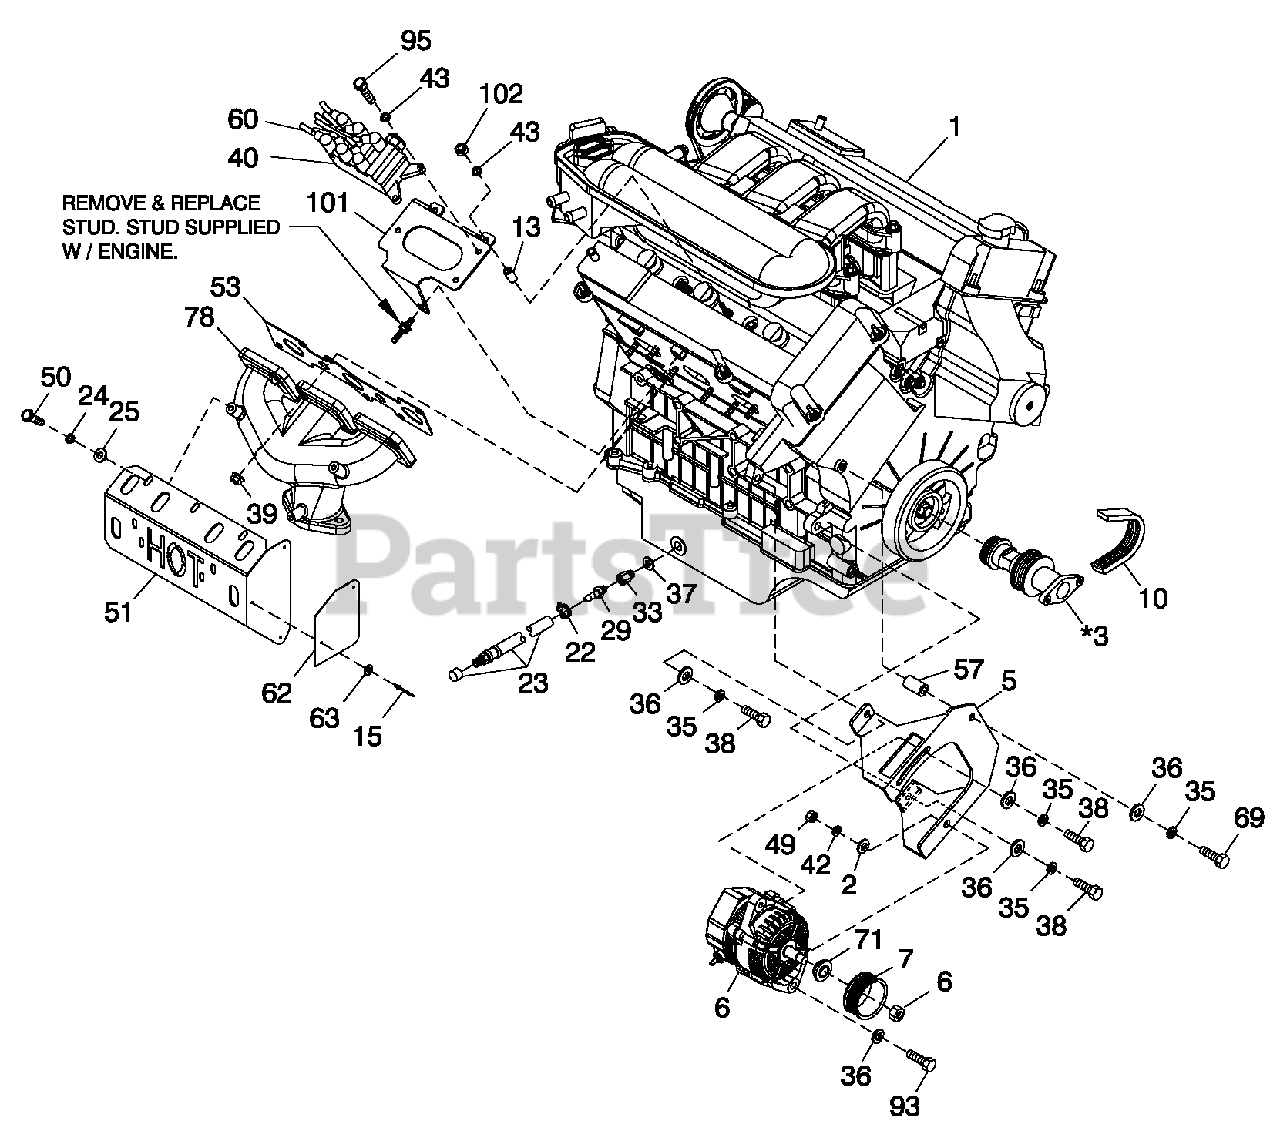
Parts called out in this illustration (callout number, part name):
1	ENGINE FWD MAKE
2	WASHER FLAT 3/8-M10 ZINC
3	ADAPTER CRANKSHAFT
4	TIE WRAP UL 17.7 X .35 BLK HT
5	BRACKET DC ALTERNATOR
6	ALTERNATOR DC W/OUT PULLEY
7	PULLEY 80 OD DC ALTERNATOR
8	SUPPORT COOLANT TUBE
9	OIL FILTER
10	BELT SERPENTINE 28.92"
11	SPACER FLEX PLATE
12	WASHER SHAKEPROOF EXT 5/16 STL
13	SPAC ER.19 X .31 X .50 PL
14	SWITCH HI-TEMP 245D X 3/8 NPT
15	RIVET POP .125 X .400 AL
16	STARTER 12 VOLT
17	COVER IAC ACTUATOR
18	ADAPTER ENGINE
19	FLEX PLATE 2 POLE
20	BSHG RDCR HEX 3/8 TO 1/8 GALV
21	SWITCH OIL PRESSURE 10 PSI 2 POL
22	CLAMP HOSE .38-.87
23	HOSE DRAIN ASSY 28"
24	WASHER LOCK 1/4-M6SS
25	WASHER FLAT 1/4 SS
26	WASHER FLAT .45X1.00
27	CAP ANTIFREEZE RUBBER
28	CLAMP HOSE #10.56-1.06
29	BARBED STR 3/8 NPT X 3/8
30	SCREW HHC M6-1.0X 16 G8.8
31	WASHER LOCK M6-1/4
32	WASHER FLAT 1/4-M6 ZINC
33	ADAPTER M12-1.75X 3/8 NPT
34	BARBED EL 90 1/2 NPT X 3/4 HOSE
35	WASHER LOCK M8-5/16
36	WASHER FLAT 5/16-M8 ZINC
37	WASHER NYLON .50 X .87 X .06
38	SCREW HHC M8-1.25X25G8.8
39	NUT HEX FLWHIZ M8-1.25
40	COIL IGNITION
41	SCREW HHC M10-1.0X25G10.9
42	WASHER LOCK M10
43	WASHER LOCK M5
44	SCREW HHC M10-1.5 X 45 G8.8 FT
45	SCREW HHC M6-1.0X 12 G8.8
46	WASHER LOCK M12
47	WASHER FLAT M12
48	WASHER SHAKEPROOF EXT 7/16 STL
49	NUT HEX M10-1.5 G8YEL CHR
50	SCREW HHC 1/4-20X1/2 SS
51	HEAT SHIELD 260X80 HOT
52	MANIFOLD EXHAUST LH
53	GASKET EXHAUST
55	PLUG EXPANSION 14 OD
56	SCREW HHC M8-1.25X20 G8.8
57	SPACER ALTERNATOR
58	WASHER FLAT M5
59	SCREW HHC M12-1.75 X 20 G8.8
60	WIRES, SPARK PLUG
61	DECAL REFER TO OWNERS MANUAL
62	REFLECTIVE HEAT SHIELD
63	WASHER FLAT #6 ZINC
64	PUMP WATER
65	TENSIONER WATER PUMP
66	BELT WATER PUMP
67	HOSE COOL 3/4 ID 20R3 (51.5" LG)
68	TUBE UPPER COOLANT
69	SCREW HHC M8-1.25X50G8.8
70	SCREW HHC M10-1.5X60G8.8
71	SPACER DC ALTERNATOR PULLEY
72	GASKET IDLE AIR CONTRL ACT CVR
73	GASKET INTAKE ADAPTER
74	MANIFOLD INTAKE UPPER
75	GASKET INTAKE MANIFOLD UPPER
76	MANIFOLD INTAKE LOWER
77	GASKET INTAKE LOWER
78	MANIFOLD EXHAUST RH
79	CLAMP VINYL 1.5 X .281 Z
80	HOSE UPPR RAD REAR
81	HOSE, LOWR RAD REAR
82	CLAMP HOSE #28 1.32-2.25
83	ADAPTER THERMOSTAT
84	GASKET THERMOSTAT
85	THERMOSTAT 195 DEG
86	MACHINING-THERMOSTAT ADPTR
87	BRACKET,THERMOSTAT
88	SCREW THF M6-1X16 N WA Z/JS
89	SCREW HHC M8-1.25X80 G8.8
90	NUT HEX M8-1.25 G8 CLEAR ZINC
91	SCREW HHC M6-1.0X 25 G8.8
92	HOSE UPPR RAD REAR
93	SCREW HHCM10-1.5X50 G8.8
94	SCREW HHTT M5-0.8X 10 BP
95	SCREW HHC M5-0.8X 25 G8.8
96	GUARD WATER PUMP REAR
97	GUARD WATER PUMP FRNT
98	BRKT WATERPUMP GUARD
99	EGRGASKET
100	COVEREGR
101	BRACKET COIL
102	NUT HEX M5-0.8 G8 CLEAR ZINC
103	SCREW SHC M8-1.25 X 30 G12.9
104	ASSEMBLY HOSE PCV VALVE
105	SCREW HHC M6-1.0X 80 G8.8
106	WATER TUBE ASSY 3.0L G3 FWD
107	DIPSTICK TUBE
109	ACCESSORY DRIVE PULLEY
